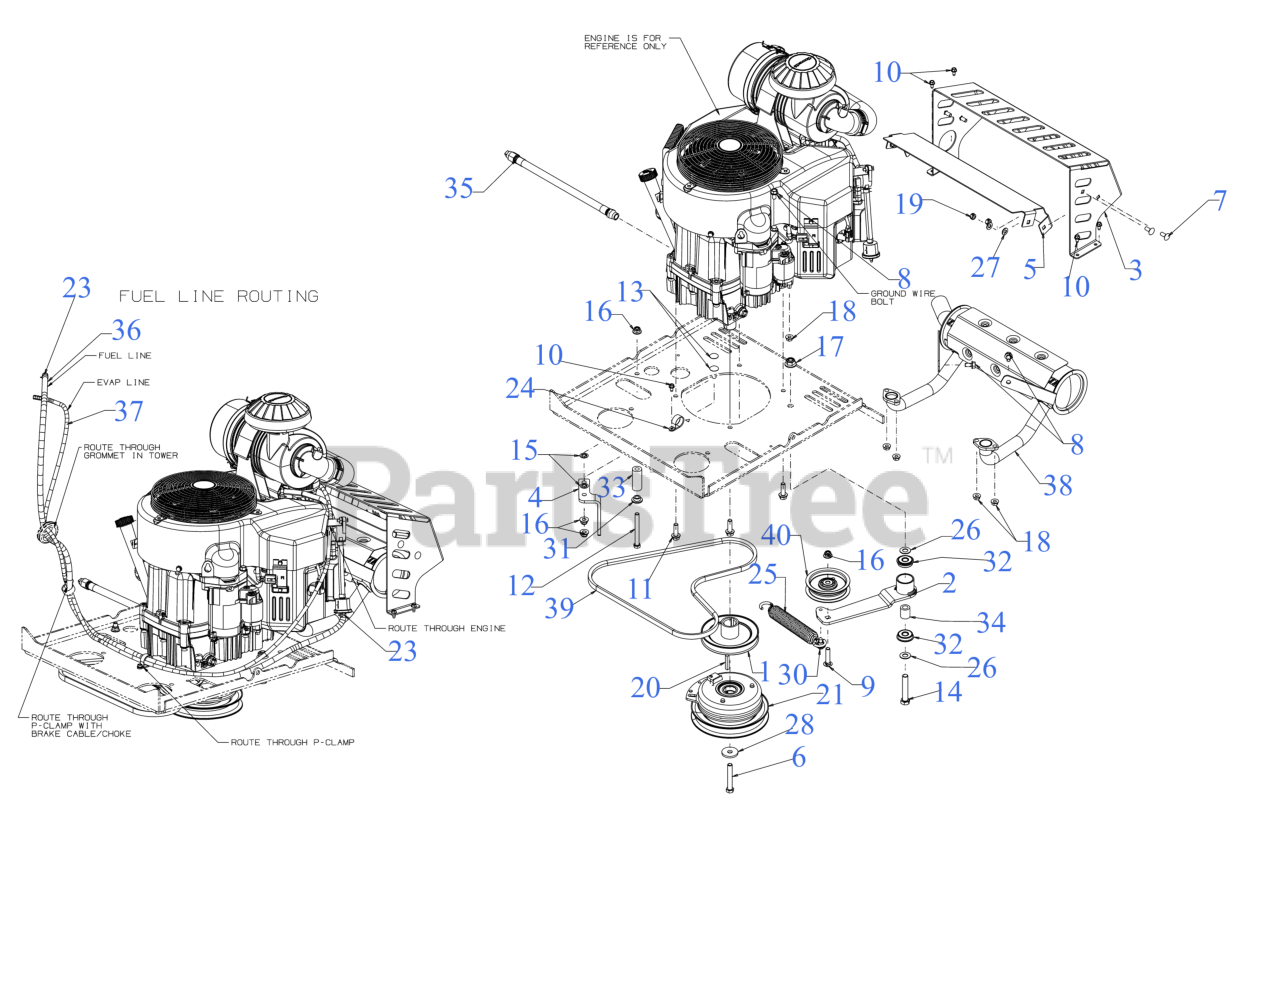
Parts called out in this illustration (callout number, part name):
1	PULLEY
2	IDLER BRACKET ASSEMBLY
3	MUFFLER SHIELD
4	CLUTCH BRACKET
5	INNER MUFFLER SHIELD
6	SCREW 7/16-20:2.75 GR5
7	CARRIAGE BOLT 5/16-18 x .75
8	SCREW M8 x 1.25 x 16MM GR8.8
9	CARRIAGE BOLT 3/8-16 x 1.75 GR5
10	SCREW 1/4-20 X.500
11	SCREW 3/8-16 x 1.25 GR5
12	SCREW 3/8-16 x 3.50 GR5
13	CARRIAGE BOLT 3/8-16 x 1.00 GR5
14	SCREW 1/2-13 x 2.75 GR5
18	HEX FLANGE NUT
19	HEX NUT LOCK CENTER
20	SQUARE KEY 1/4 x 1.50
21	ELECTRIC PTO CLUTCH
23	HOSE CLAMP 1/20
24	DRAIN HOSE CLAMP
25	SPRING 1.25" DIA x 8.5" LONG
26	FLAT WASHER .510X.995
27	FLAT WASHER
28	FLAT WASHER .45 x 1.5 x .172 HT
30	SHOULDER SCREW .43X.29X5/16-18 TT
31	SHOULDER SPACER
32	ROLLER BEARING .5X1.37X.44
33	SPACER .41 x .875 x 2.19
34	SPACER 0.51 x 0.88 x 1.00
35	OIL DRAIN HOSE
36	FUEL HOSE LOW PERMEATION 54"
37	VENT HOSE 3/16 ID 70"LG
39	BELT SEC A x 51.18
40	FLAT IDLER PULLEY 3.5
